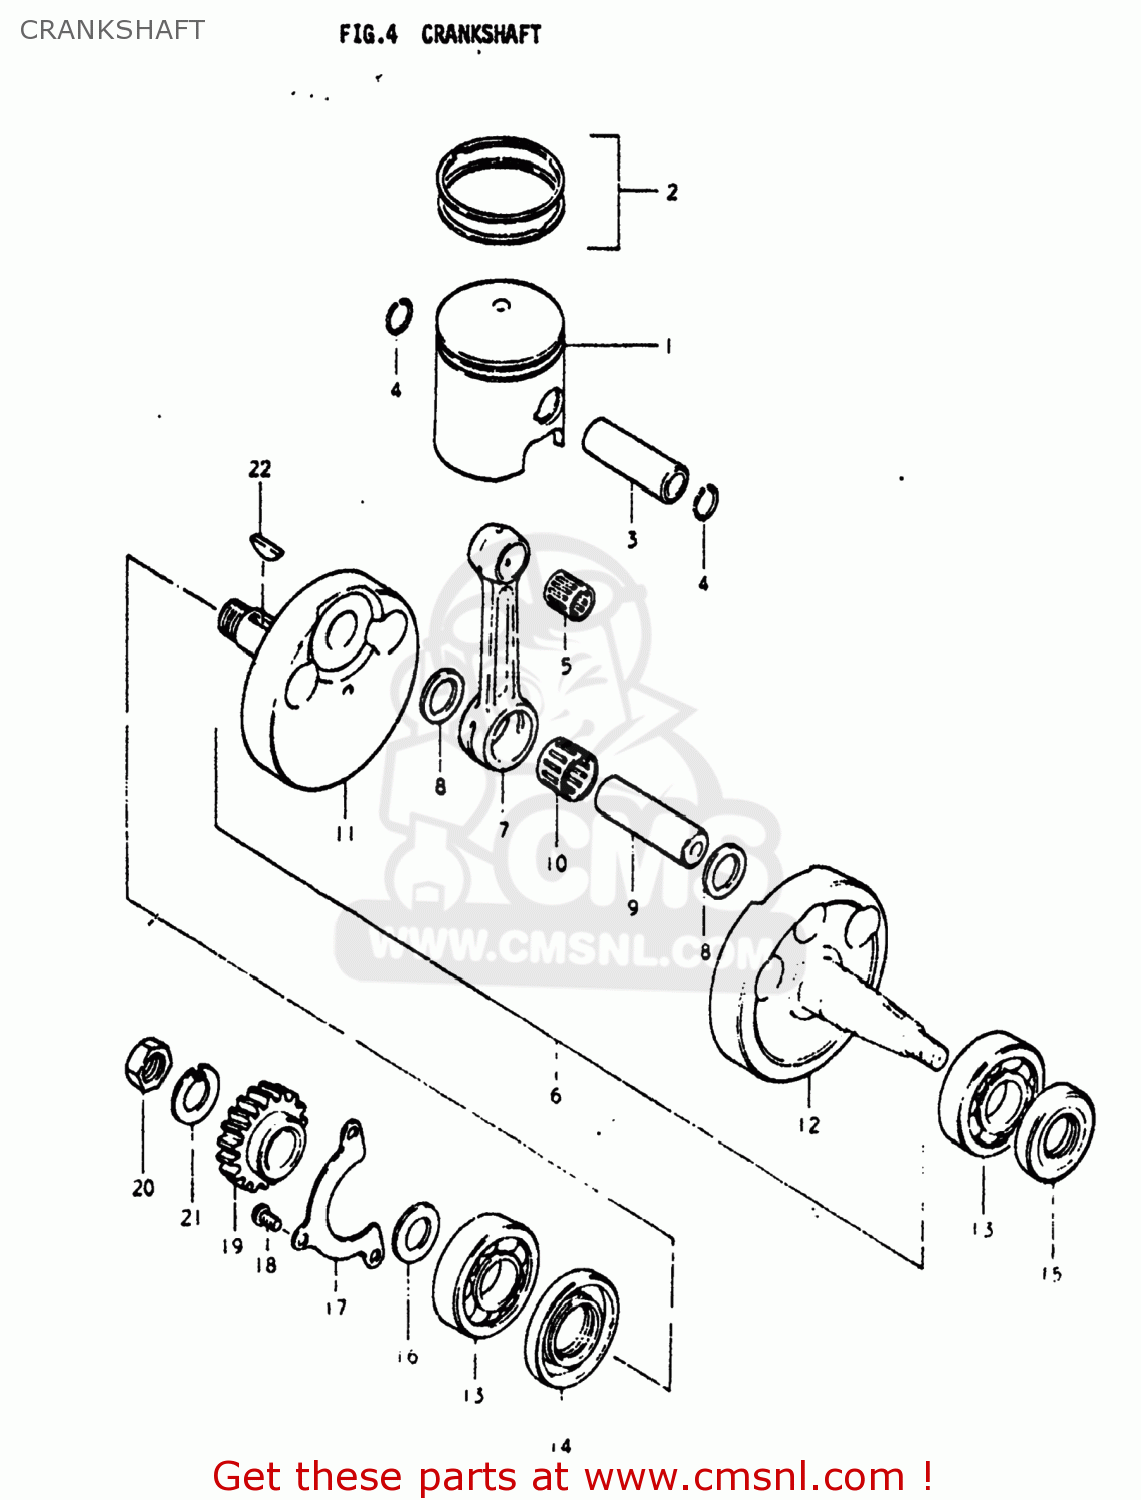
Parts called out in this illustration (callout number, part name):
1	PISTON
2	RING SET,PISTON
3	PIN,PISTON (18MM)
4	CIRCLIP
5	BEARING(18X23X22)
6	CRANKSHAFT ASSEMBLY
7	CONNECTING ROD
8	WASHER(24X29X1.5)
9	PIN,CRANK
10	BEARING
11	CRANKSHAFT
12	CRANKSHAFT,LEFT
13	BEARING
14	SEAL,OIL(35X62X9)
15	SEAL,OIL(24X50X9)
16	WASHER(20X48X1)
17	PLATE
18	SCREW 6X12
19	GEAR,PRIMARY DRIVE
20	NUT
21	WASHER
22	KEY
